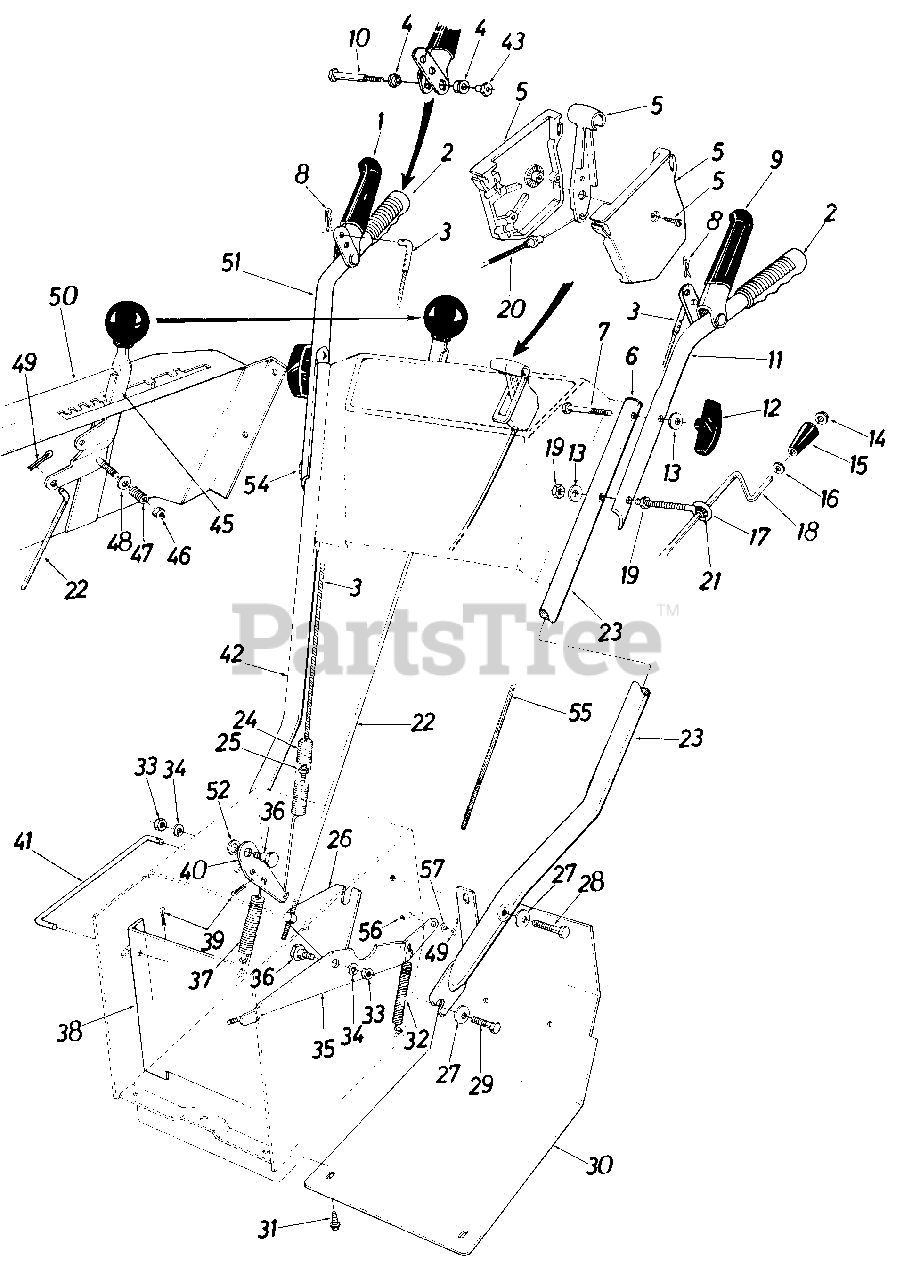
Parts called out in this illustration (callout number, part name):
1	Clutch Grip Ass'y. R.H.
2	Hand Grips
3	Lockout Cable 30.5" Lg.
4	Hex Flange Brg. Plastic .38" I.D.
5	Throttle Control Box Ass'y.
6	Plastic Plug
7	Hex Bolt 5/16-18 x 2.0" Lg.
8	Hairpin Cotter
9	Clutch Grip Ass'y. L.H.
10	Shld. Bolt .374" Dia. x 1.53" Lg.
11	Upper Handle Half L.H.
12	Hand Knob
13	Belleville Wash. 5/16" I.D.
14	Push Nut 3/8 Rod
15	Knob 3/8 I.D.
16	Fl-Wash. .40 I.D. x .62 O.D. x .060
17	Eyebolt
18	Chute Crank Ass'y.
19	Hex Nut 5/16-18 Thd.
20	Throttle Wire
21	Chute Crank Grommet
22	Shifting Rod
23	Lower Handle Half L.H.
24	Extension Spring .75" O.D. x 5.0" Lg.
25	Hex Ins. L-Nut 1/4-20 Thd.
26	Shifting Linkage Bracket
27	Bellevi I le Wash. .40 I.D. x .88 O.D. x .060
28	Hex Bolt 3/8-16 x 2.0" Lg.
29	Hex Wash. Hd. Self-Tap Scr. 3/8-16 x .75" Lg.
30	Frame Cover
31	Hex Wash. Hd. Self-Tap Scr. 1/4-20 x .50" Lg.
32	Extension Spring 38" O.D. x 3.25 Lg.
33	Hex Jam Nut 3/8-16 Thd.
34	L-Wash. 3/8" l.D.
35	Auger Clutch Brk't. Ass'y.
36	Shld. Bolt .625" Dia. x .170" Lg. (3/8-16)
37	Extension Spring .75" O.D. x 4.31" Lg.
38	Drive Pulley Support Brk't. Ass 'y.
39	Cotter Pin 3/32" Dia. x .75" Lg.*
40	Drive Clutch Brk't.
41	Drive Clutch Rod
42	Lower Handle Half R.H.
43	Shld. Nut 1/4-20 Thd.
45	Shift Handle Ass'y.
46	Hex Ins. Jam L-Nut 3/8-24 Thd.
47	Compression Spring .38" O.D. x .88" Lg.
48	Bell-Wash. .40 I.D. x .88 O.D. x .060
49	Cotter Pin 3/32" Dia. x .75" Lg.
50	Handle Panel Ass'y.
51	Upper Handle Half R.H.
52	Bell-Wash. .38 I.D. x 1.12" O.D. x .02
54	Carriage Bolt 5/16-18 x 2.50" Lg.
55	Lockout Cable 36n Lg.
56	Adjustment Ferrule
57	Fl-Wash. .33n l.D. x .63" O.D.
